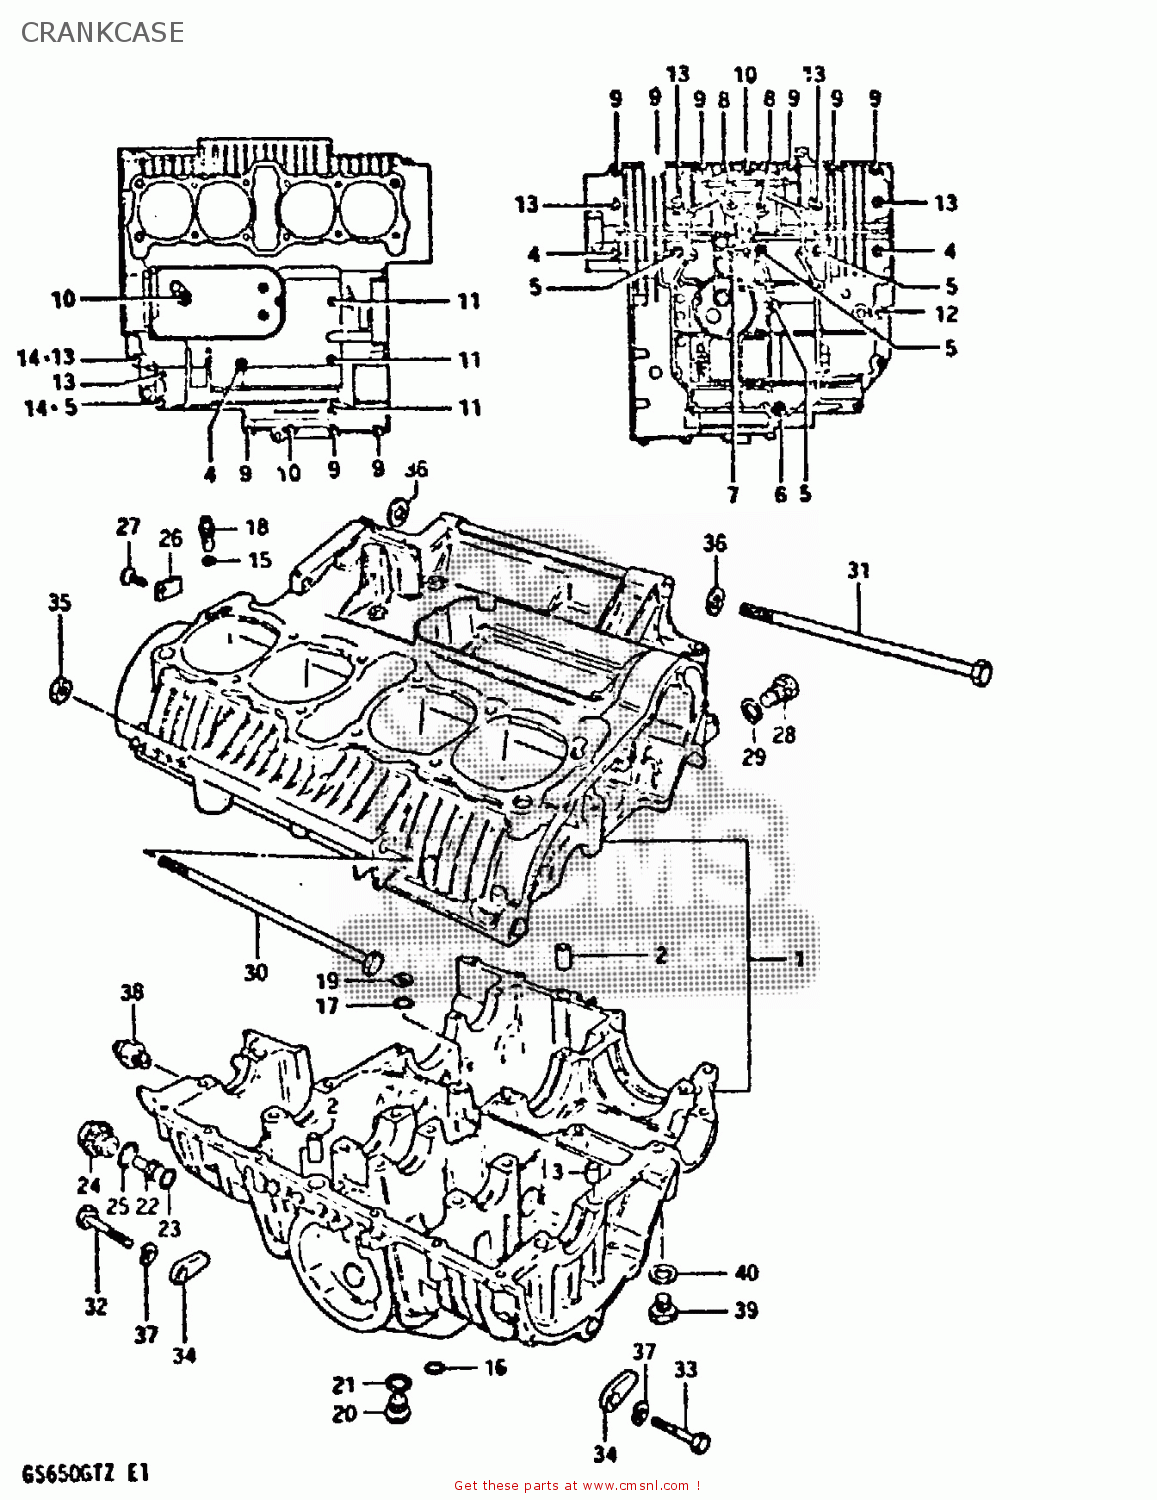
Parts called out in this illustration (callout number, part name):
1	CRANKCASE SET
2	PIN (11X20)(SUS)
3	PIN(10.4X13X22)
4	BOLT
5	BOLT
6	BOLT(8X135)
7	BOLT(8X140)
8	BOLT
9	BOLT
10	BOLT
11	BOLT (6X90)
12	BOLT (8X70)
13	BOLT (8X95)
14	NUT
15	O-RING,OIL GALLERY JET
16	O-RING
17	O RING(D:3.2,ID:12.9)
18	JET(12)
19	WASHER
20	PLUG
21	GASKET(16X22X2) (NAS)
22	PIN,OIL GALLERY
23	SEAL (D:1.9 ID:9.8)
24	PLUG
25	O RING(D:2.4,ID:17.8)
26	PLATE,OIL GALLERY PLUG
27	SCREW
28	PLUG
29	GASKET(12.1X16.2X3.7) (NAS)
30	BOLT
31	BOLT 10X250
32	BOLT 10X55
33	BOLT 10X40
34	NUT
35	NUT 10MM
36	WASHER
37	LOCK WASHER
38	SWITCH ASSEMBLY
39	PLUG
40	GASKET(14X19.2X2) (NAS)
